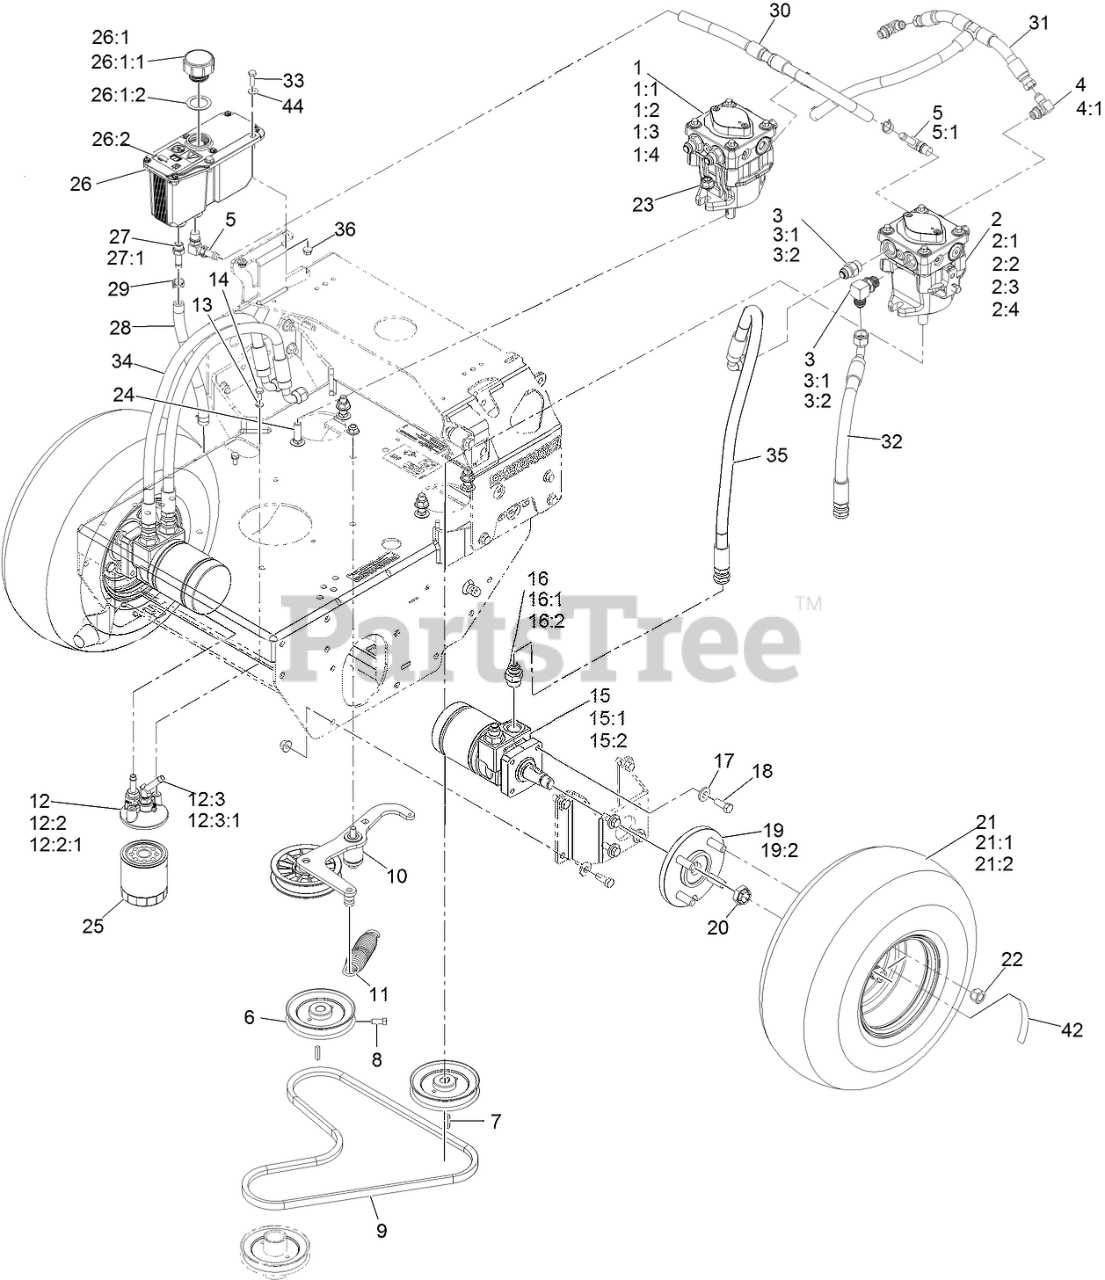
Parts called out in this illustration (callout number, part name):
1	RH HYD PUMP ASM
1:1	INPUT SHAFT KIT
1:2	BEARING-THRUST
1:3	CYLINDER BLOCK KIT
1:4	SEAL OVERHAUL KIT
2	LH HYD PUMP ASM
2:1	INPUT SHAFT KIT
2:2	BEARING-THRUST
2:3	CYLINDER BLOCK KIT
2:4	SEAL OVERHAUL KIT
3	FITTING-STRAIGHT
3	FITTING-90 DEG
4	FITTING-ELBOW, 90 DEG
4:1	O-RING
5	FITTING-ELBOW, 90
5:1	O-RING
6	SHEAVE ASM
8	SCREW-SET, SQH
9	BELT
10	ASM, PUMP IDLER
11	SPRING-EXTENSION
12	ASM, FILTER HEAD
12:2	ADAPTER-STRAIGHT
12:2:1	O-RING
12:3	FITTING-BARBED, 45 DEG
12:3:1	O-RING
13	WASHER-LOCK
14	SCREW-HH
15	HYD MOTOR ASM
15:1	SEAL KIT
15:2	BEARING AND SEAL KIT
16	FITTING-STRAIGHT
16:1	O-RING
17	WASHER-BELLEVILLE
18	SCREW-HH
19	WHEEL HUB ASM
19:2	STUD-WHEEL
20	NUT-LOCK
21	WHEEL AND TIRE ASM
21:1	TIRE-TURFMASTER
21:2	RIM-WHEEL
22	NUT-LUG
23	NUT-HF, NI
24	BOLT-CARR
25	FILTER-25 MICRON, BI-DIRE
26:1	Reservoir-HYD
26:1:1	Cap-Reservoir, HYD
26:1:2	GASKET-CAP
26:2	DECAL-WARNING
27	ADAPTER-STRAIGHT
27:1	O-RING
28	HOSE-CHARGE
29	CLAMP-HOSE
30	HOSE-CASE DRAIN
31	HOSE-CHARGE
32	ASM, HP HOSE
33	SCREW-HH
34	HYD HOSE ASM
35	HYD HOSE ASM
36	NUT-HHF
42	DECAL-TORQUE WHEEL LUG-HU
44	WASHER-FLAT
